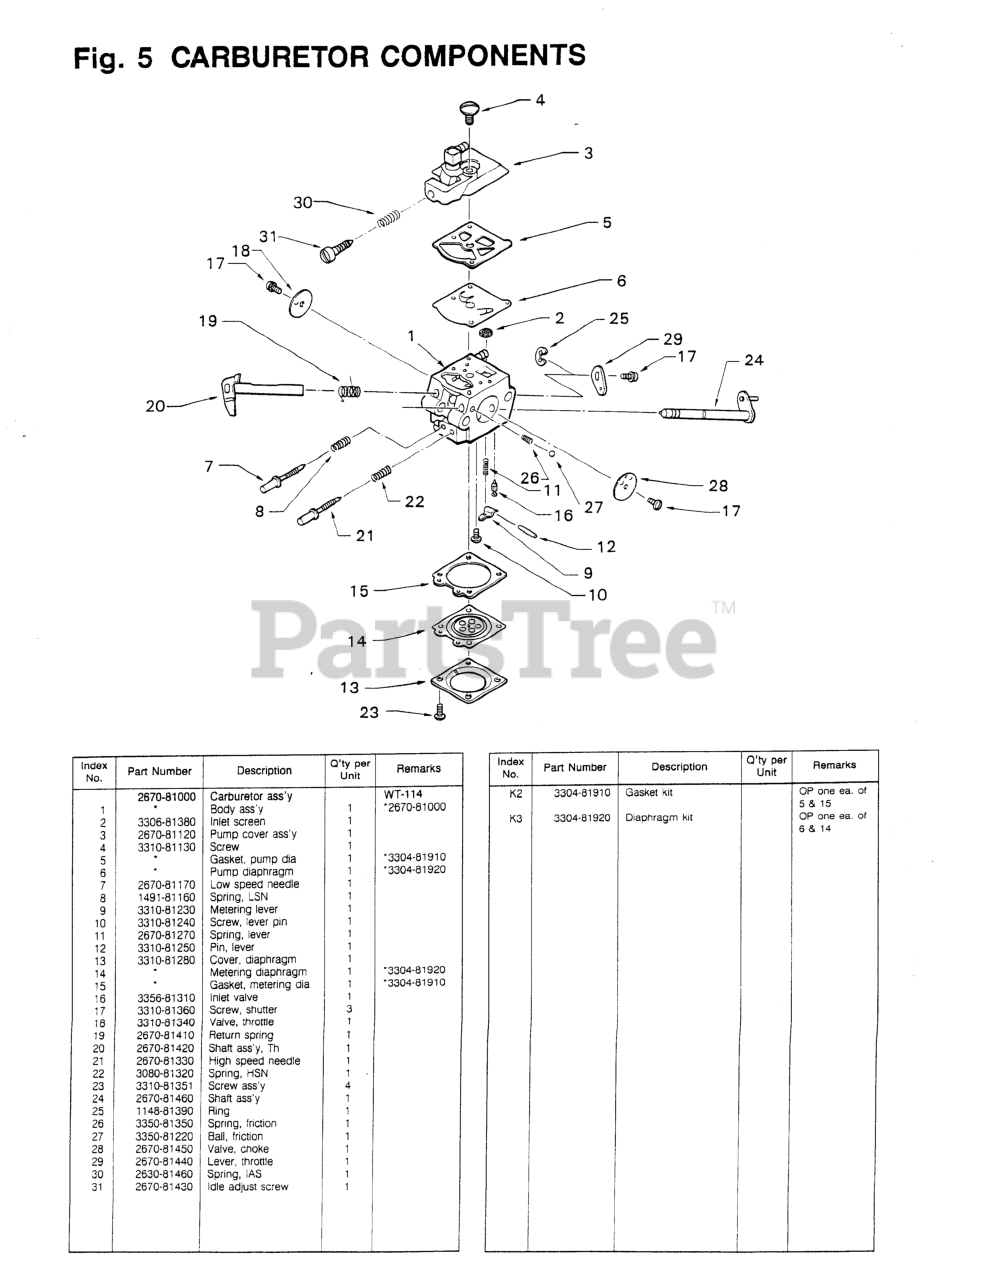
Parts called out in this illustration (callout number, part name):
3	COVER ASSEMBLY
5	KIT ONLY
9	LEVER
12	PIN, METERING LEVER
15	KIT ONLY
16	VALVE, INLET
19	SPRING, RETURN
20	SHAFT ASSEMBLY
21	NEEDLE, HI-SPEED
23	SCREW ASSEMBLY
26	SPRING
27	BALL, FRICTION
28	VALVE, CHOKE
29	VALVE, THROTTLE
30	SPRING, IDLE
NI	KIT ONLY
